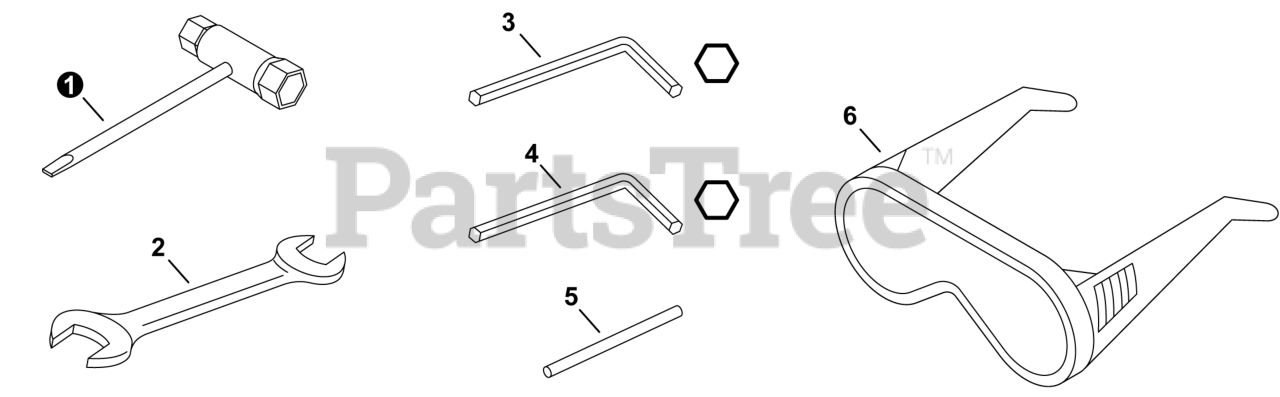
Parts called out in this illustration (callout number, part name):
1	T-WRENCH 17x19
2	SPANNER 8x10
3	WRENCH, ALLEN M4
4	WRENCH, ALLEN M5
5	TOOL, LOCKING
6	GLASSES, SAFETY
